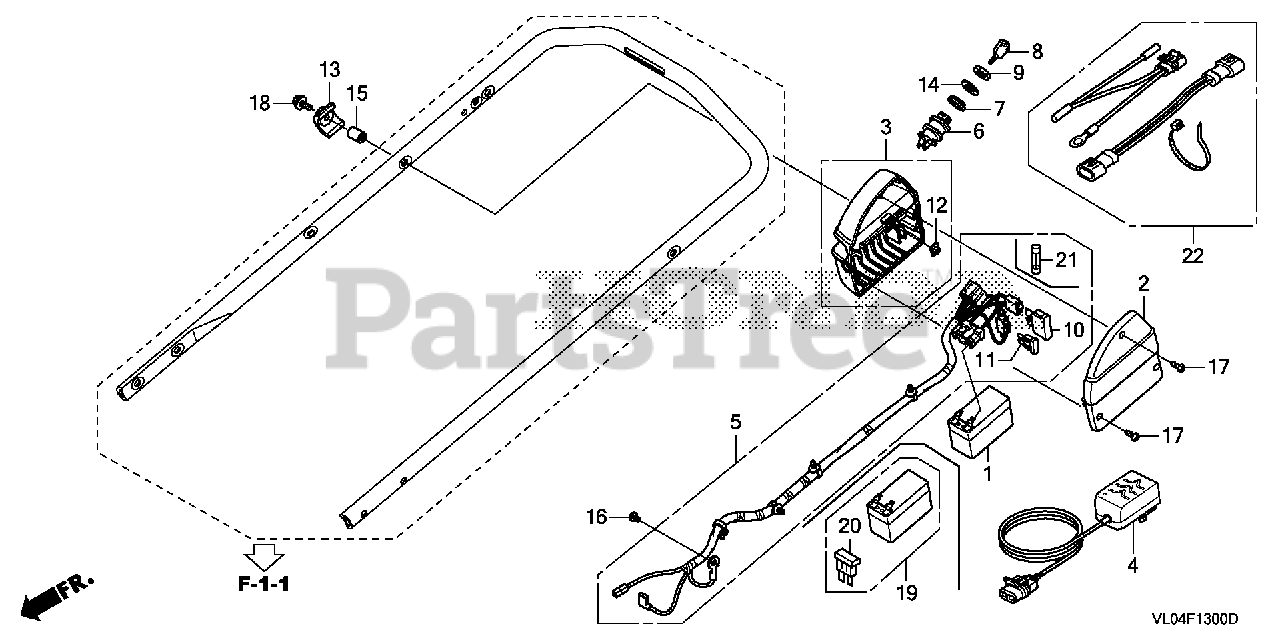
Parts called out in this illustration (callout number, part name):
1	BATTERY ASSY. (MSDS)
2	COVER, BATTERY
3	BOX, BATTERY
4	CHARGER ASSY., BATTERY (FLOAT-CHG) (WITH 06320-VH7-S00)
5	HARNESS ASSY., MAIN
6	SWITCH ASSY., MOMENT
7	BASE, MOMENT SWITCH
9	NUT, SWITCH
11	FUSE, BLADE (3A)
12	NUT, SPECIAL (6X7)
13	WASHER, FRAME JOINT
14	WASHER, SWITCH
15	COLLAR, BATTERY MOUNTING
16	SCREW, PAN (5X8)
17	SCREW, TAPPING (4X16)
18	BOLT, FLANGE (6X35)
21	FUSE A (30A) (SLO-BLO)
22	CHARGER KIT, HARNESS
